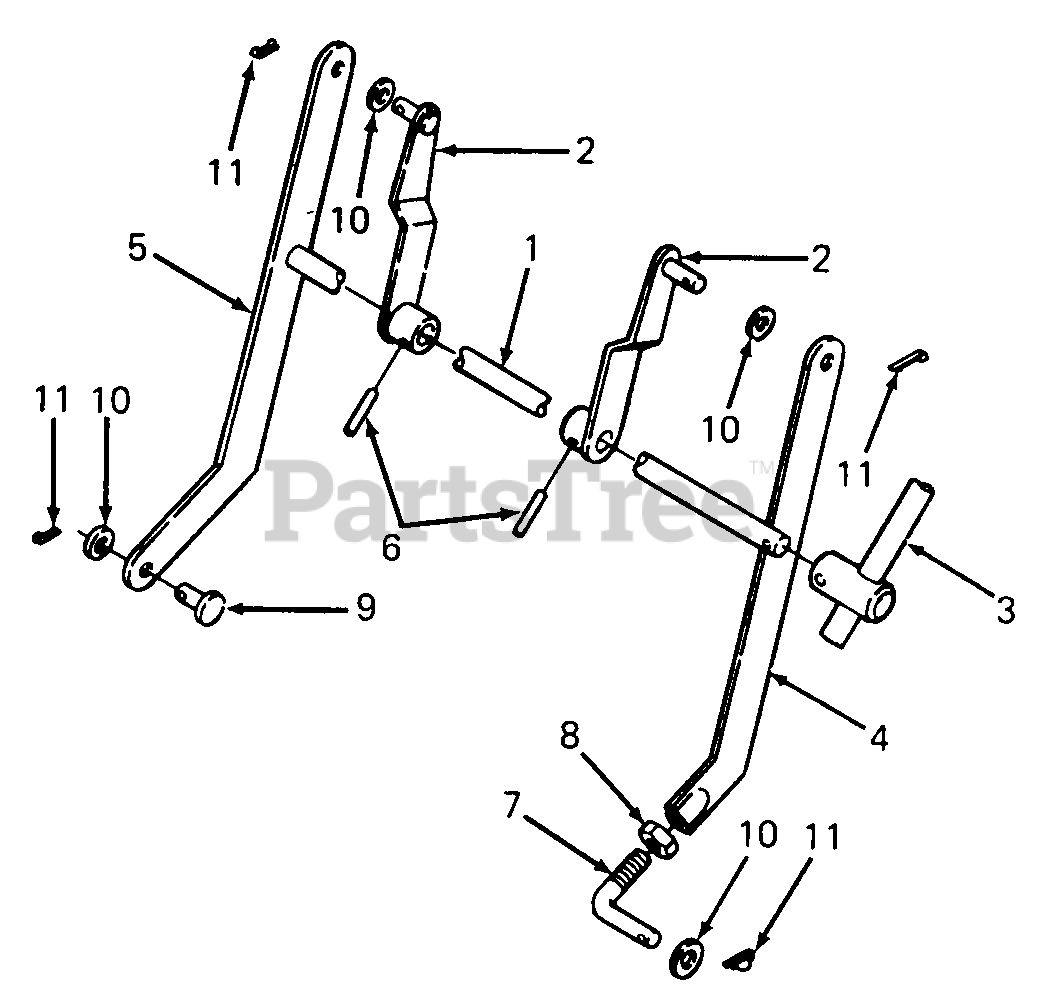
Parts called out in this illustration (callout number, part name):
1	Shaft, Lift
2	Arm, Lift
3	Lever, Lift
4	Bracket, Lift
5	Link, Lift
6	Pin, 1/4 X 1.5 Long Slotted Roll
7	Rod, Lift Link
8	Nut, 1/2-13
9	Pin, Lift Bracket
10	Washer, .510 X 1.0 X .06
11	Pin, Internal Cotter
